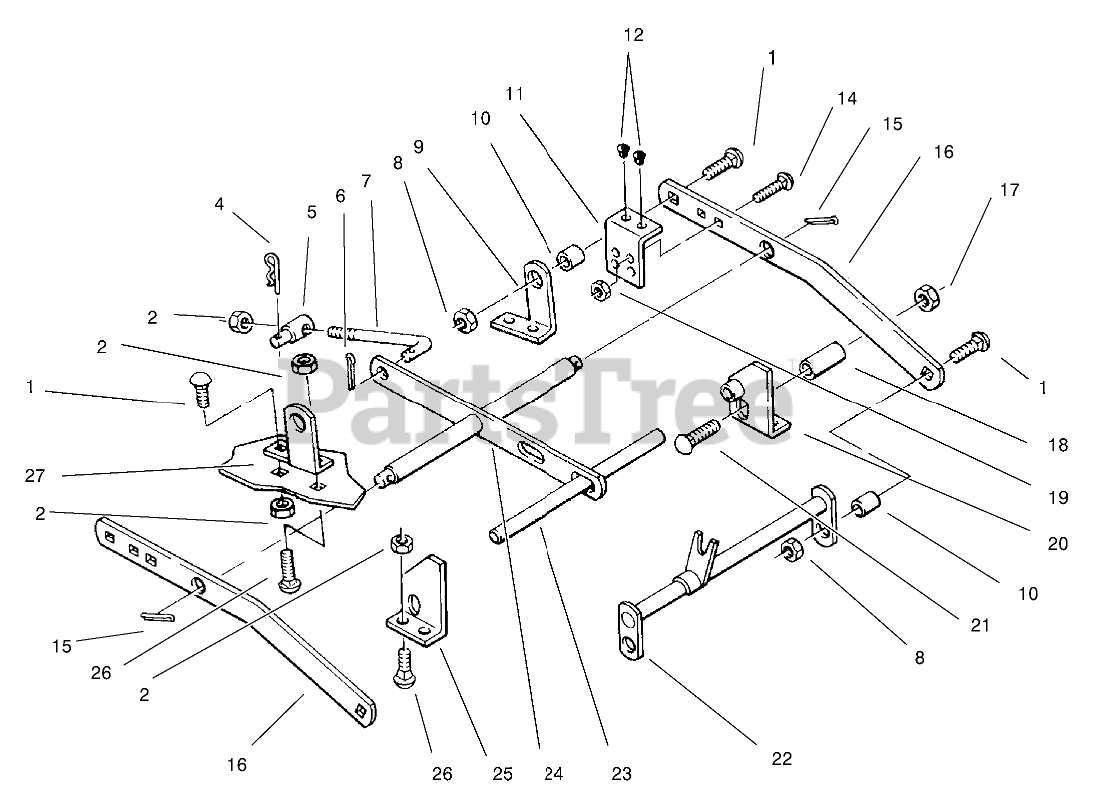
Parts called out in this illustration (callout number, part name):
1	BOLT-CARR
2	NUT-LOCK, NI
4	PIN-HAIR
5	TRUNNION-LIFT
6	PIN-COTTER
7	ROD-LEVEL ADJUST
8	LOCKNUT-FLANGE
9	LH BRKT-DECK REAR (RED)
10	SPACER
11	BUMPER (RED)
12	BUMPER-RUBBER
14	BOLT-CARR
15	PIN-COTTER
16	BAR DRAFT (RED)
17	NUT-LOCK, NI
18	SPACER
19	NUT-LOCK, NI
20	WA BRACKET FT L (RED)
21	BOLT-CARR
22	WA HITCH (RED)
23	SHAFT FRONT (RED)
24	LEVELER WA (RED)
25	WA BRACKET FT R (RED)
26	BOLT-CARR
27	RH BRKT-DECK REAR (RED)
